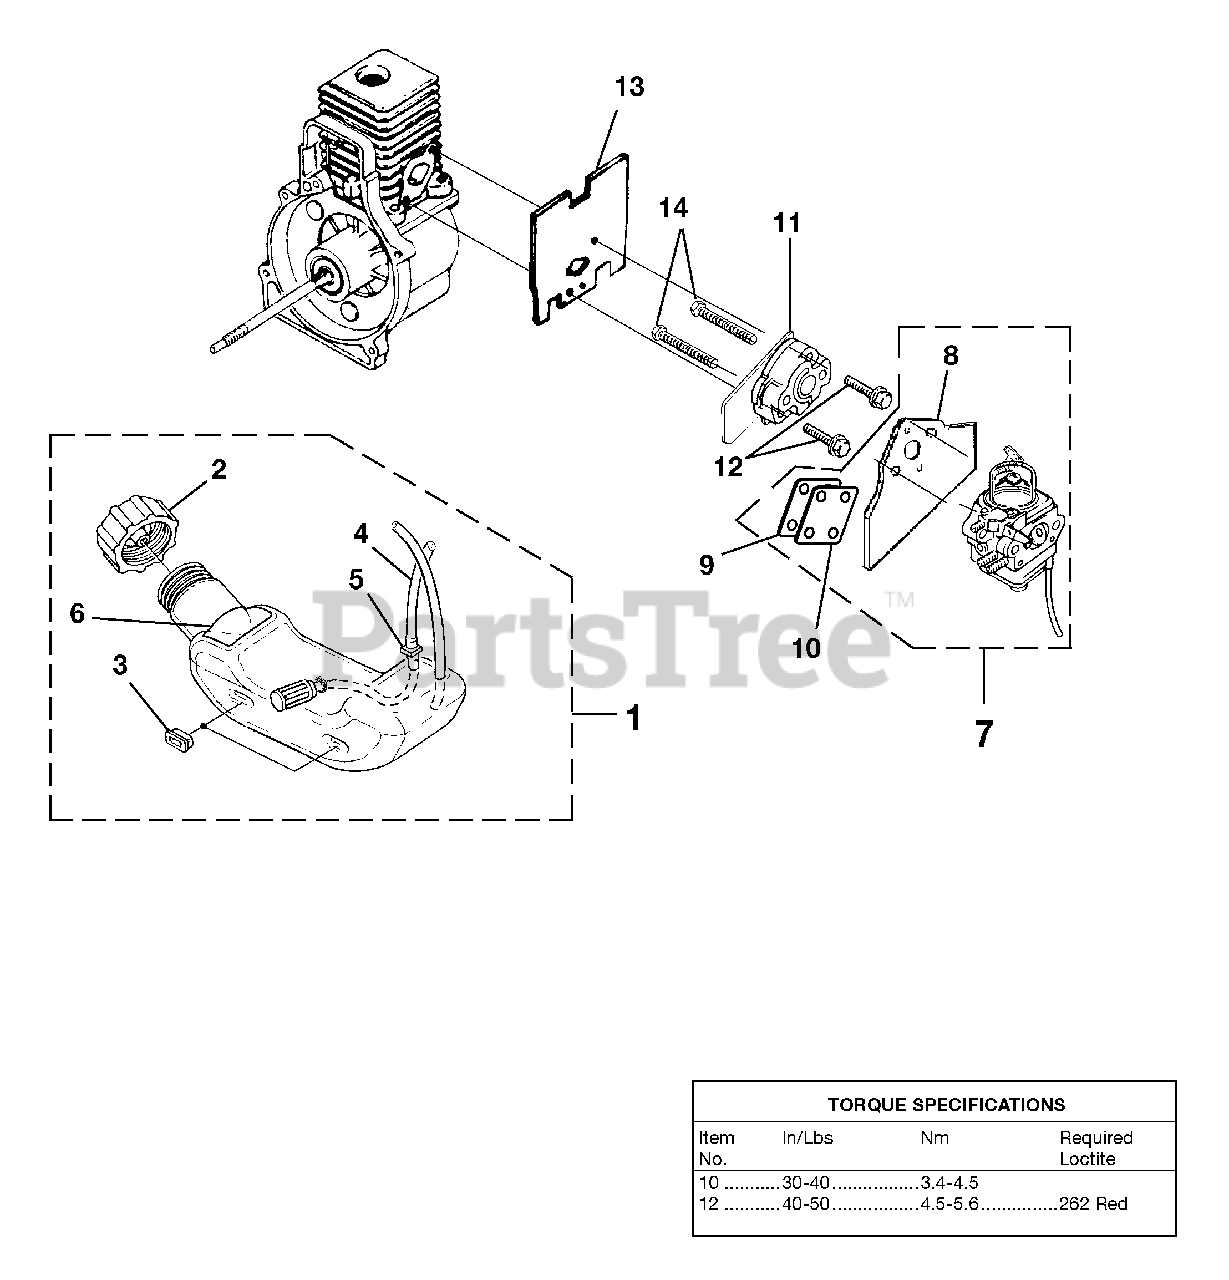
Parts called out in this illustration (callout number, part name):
1	FUEL TANK KIT (UT08929A, UT08930A)
1	FUEL TANK KIT (UT08121)
2	FUEL CAP
3	BUMPER-Rubber
4	TUBING-Rubber (3")
5	Fitting-Inlet (small for 2.5mm ID fuel line)
6	HEAT SHIELD
7	CARBURETOR KIT (UT08929A,UT08930A)
7	CARBURETOR KIT (UT08121)
8	GASKET-Carburetor
9	SPACER, PLASTIC
10	GASKET, CARBURETOR
11	HEAT DAM
12	SCREW, SEMS (10-24 x 1.110)
13	GASKET-Heat Dam
14	SCREW-Thread Form. (10-24 x 1)
